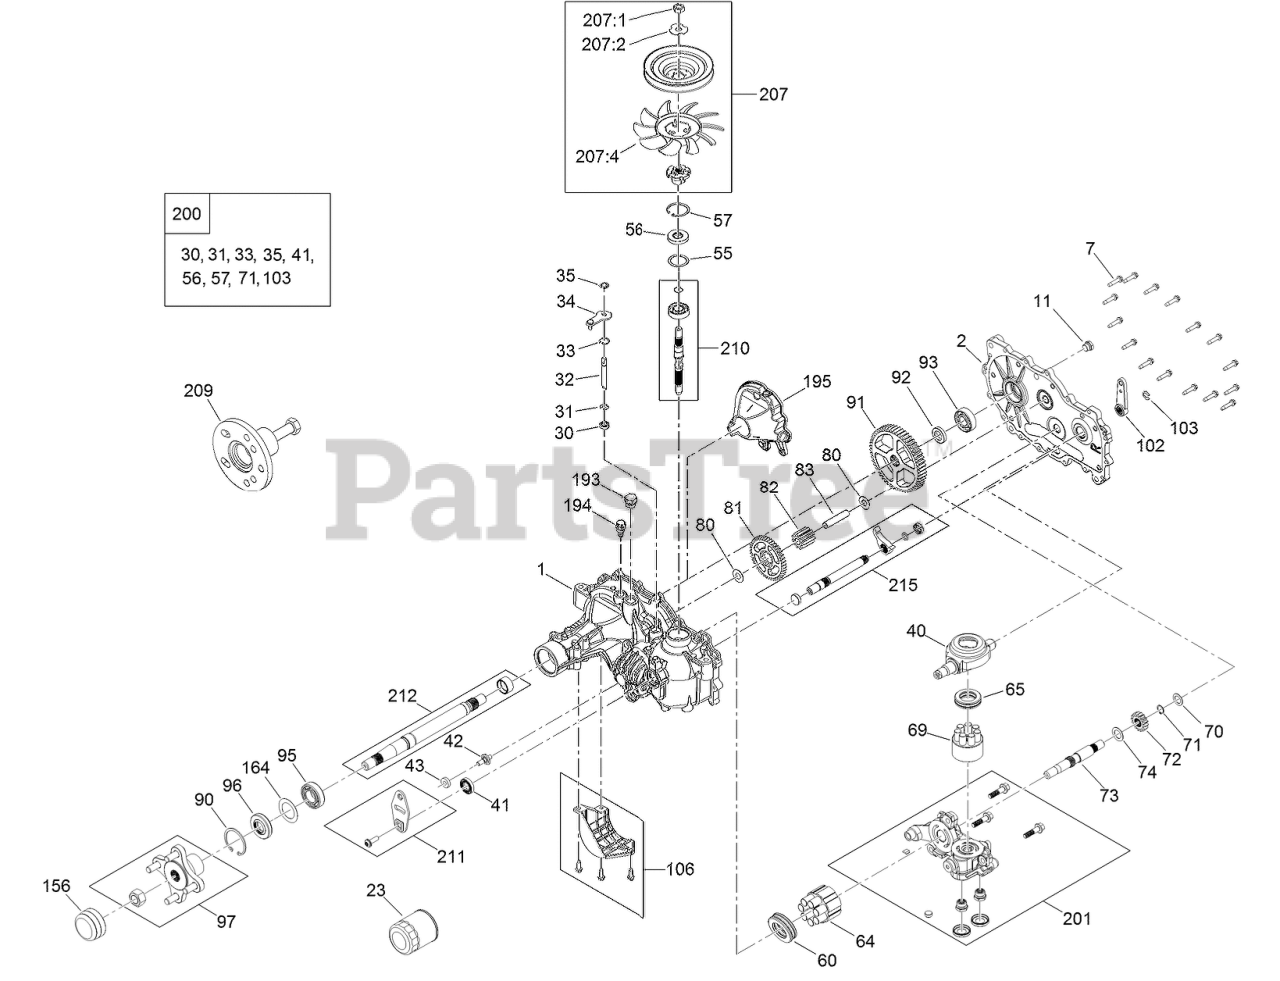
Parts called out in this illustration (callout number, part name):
1	KIT-HOUSING MAIN RH, CNTL
2	RH SIDE COVER KIT
7	SCREW-HHF
23	ELEMENT-OIL FILTER, HYD
30	SEAL-LIP
31	RING-RETAINING, EXTERNAL
32	ROD-BYPASS
33	RING-RETAINING, INTERNAL
35	RING-RETAINING, EXTERNAL
40	SWASHPLATE-TRUNNION
41	SEAL-LIP
43	PUCK-FRICTION
55	SPACER
56	SEAL-LIP
57	RING-RETAINING
60	BEARING-THRUST
64	CYLINDER BLOCK ASM KIT
65	BEARING-THRUST
69	PUMP BLOCK ASM
70	WASHER-FLAT
71	RING-RETAINING
72	GEAR-16T
73	SHAFT-MOTOR
74	WASHER
80	WASHER
81	GEAR-43T
82	GEAR-11T
83	PIN-JACKSHAFT
90	RING-RETAINING
91	GEAR-54T
92	SPACER
93	BEARING KIT
95	BEARING-BALL
97	HUB KIT
102	HANDLE-BRAKE
103	RING-RETAINING, EXT
106	FILTER GUARD KIT
156	COVER-NUT, AXLE
164	SPACER
194	BREATHER FITTING ASM
195	RH INTERNAL EXPANSION TANK ASM
200	SEAL KIT
201	RH CENTER SECTION KIT
207	FAN AND PULLEY KIT
207:1	NUT-HJ
207:2	WASHER-SLOTTED
207:4	FAN 7.0 X 10 BLADE
210	KIT-INPUT SHAFT
211	CONTROL ARM KIT
212	AXLE SHAFT KIT
215	INBOARD KIT
